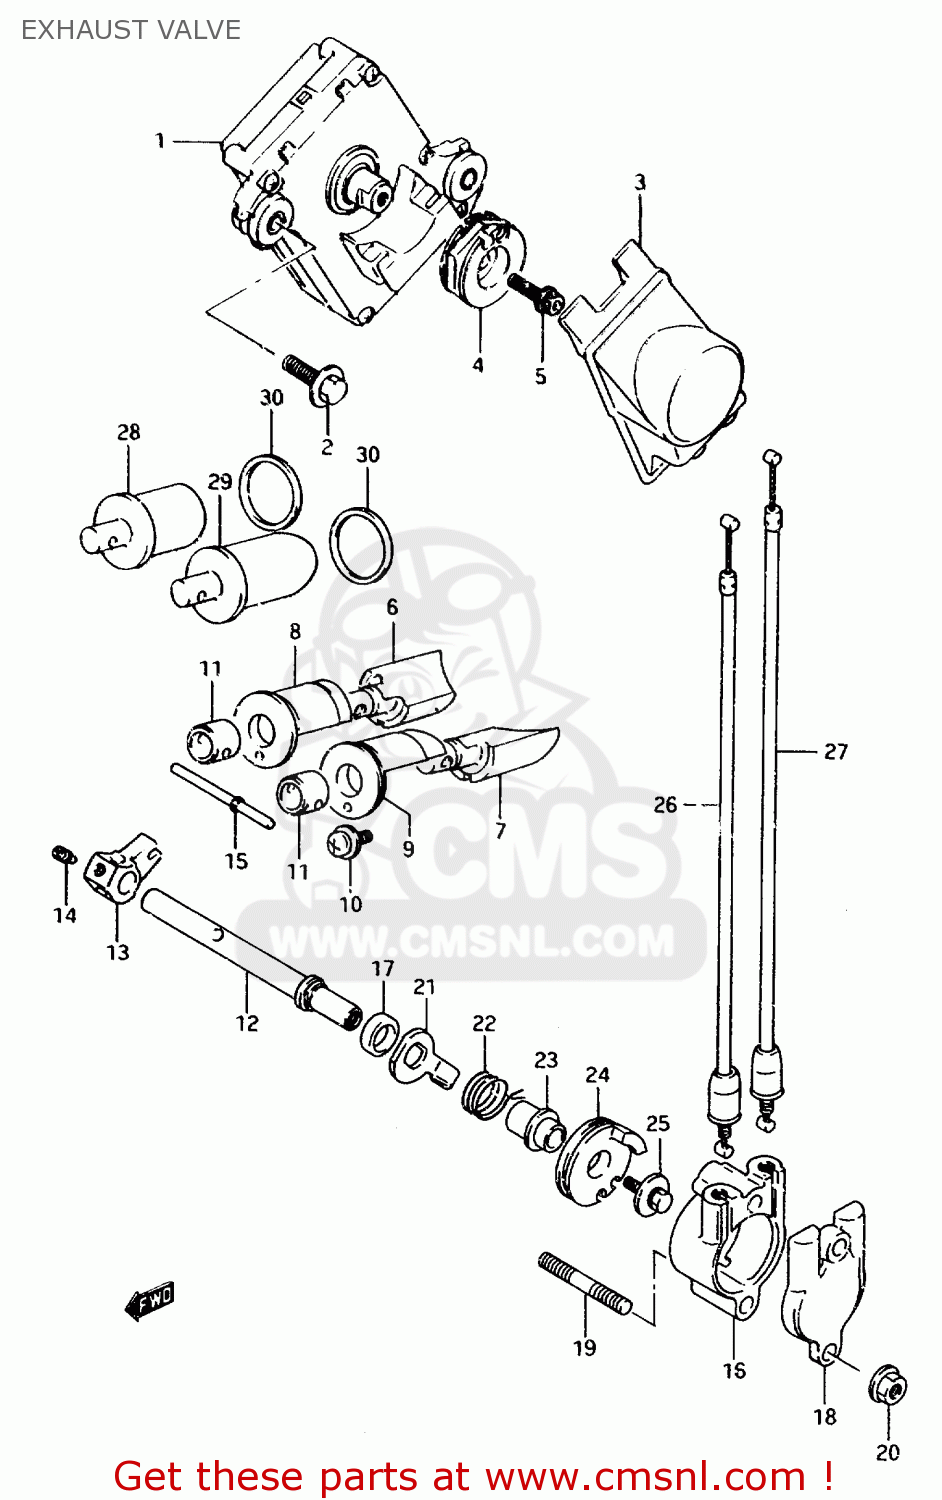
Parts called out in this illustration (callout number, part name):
1	ACTUATOR ASSY,EXHAUST VALVE
2	BOLT(6X25)
3	COVER,ACTUATOR
4	PULLEY,CONTROLLER
5	BOLT
6	VALVE,EXHAUST,R
7	VALVE,EXHAUST,L
8	GUIDE, EXHAUST VALVE RH
9	GUIDE,EXHAUST VALVE,L
10	SCREW
11	SPACER,EXHAUST VALVE
12	SHAFT, EXHAUST VALVE
13	ARM,EXHAUST VALVE SHAFT
14	SCREW(6X10)
15	PIN,EXHAUST VALVE 48.5MM
16	HOLDER,EXHAUST VALVE
17	SEAL,OIL(8X16X5)
18	COVER,HOLDER
19	STUD BOLT
20	NUT
21	LEVER,EXHAUST VALVE
22	SPRING,EXHAUST VALVE LEVER
23	SPACER,EXHAUST VALVE PULLEY
24	PULLEY, EXHAUST VALVE
25	BOLT(5X12)
26	CABLE ASSY,EXHAUST VALVE NO.1
27	CABLE ASSY,EXHAUST VALVE NO.2
28	PLUG, EXHAUST RH
29	PLUG, EXHAUST LH
30	SHIM,T:0.9
